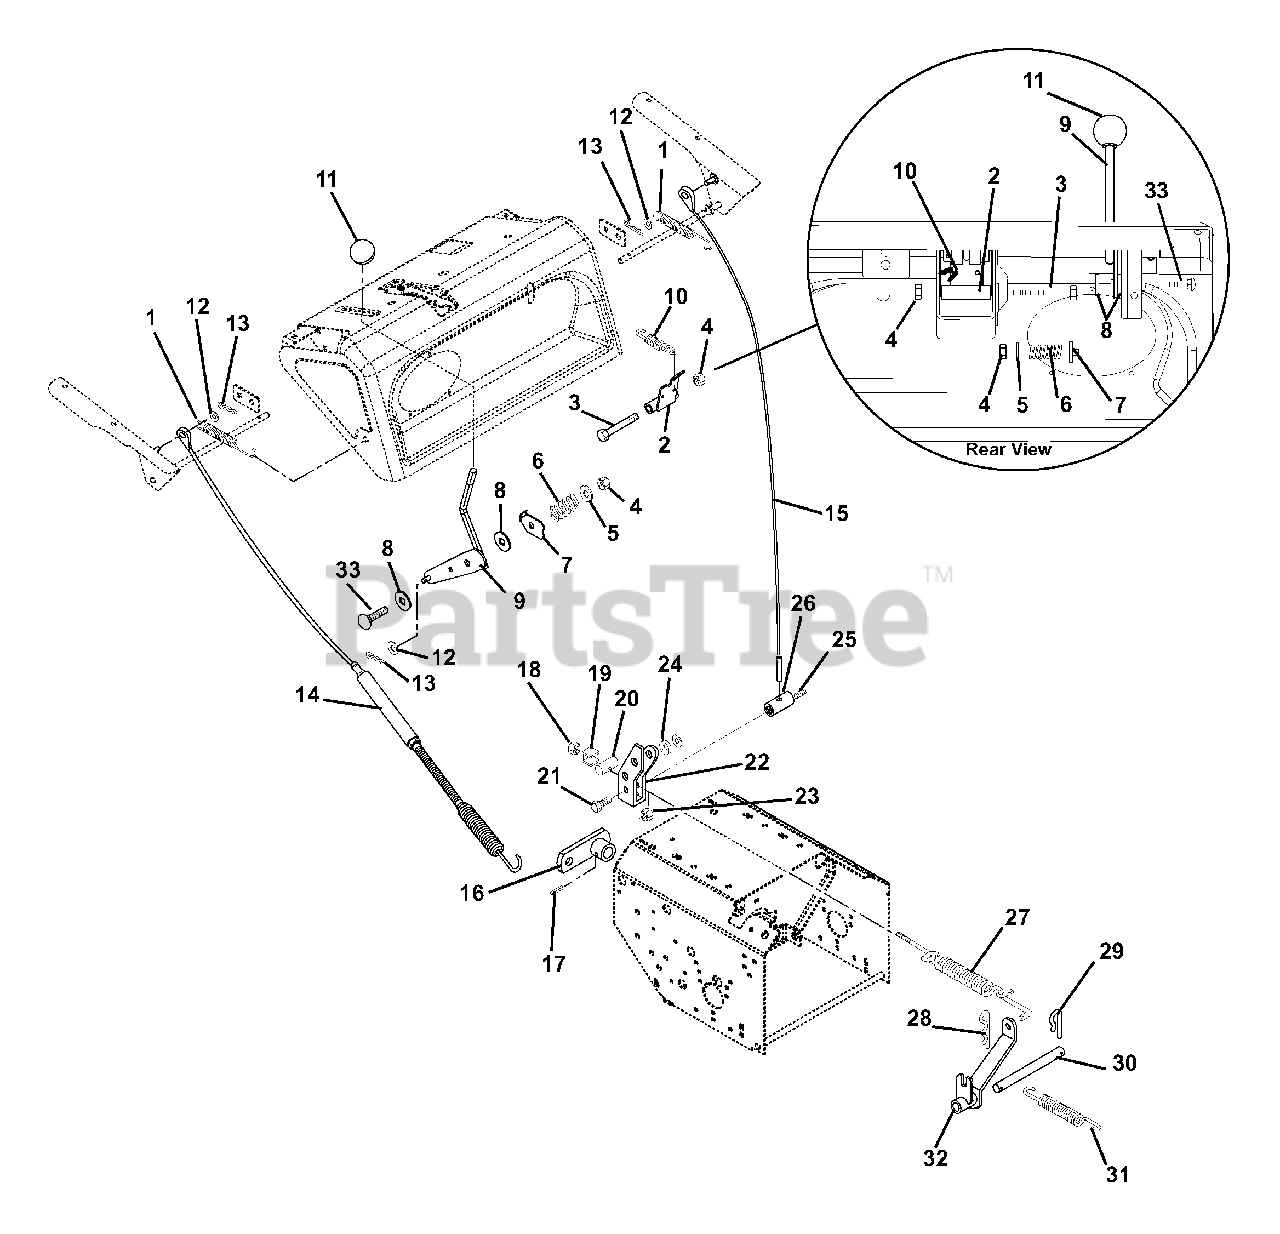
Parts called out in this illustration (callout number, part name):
1	SG-TENS .051X.50X4.87
2	ARM, INTERLOCK
3	@BLT-HEX .38-16X3.00 GR5 YWZC
4	@NUT-LK-CTR .38-16 YWZC
5	@WSHR-FL-STL.406X.812X.065 YWZ
6	SG-COMP .187X.56X1.62
7	PRESSURE FLANGE
8	FRICTION WASHER
9	LEVER, DEFLECTOR
10	SPRING-EXT .047X.438X1.45
11	KNOB,BALL -BLACK 1.47" .375-16
12	@WSHR-FL-STL.281X.62X.065 YWZC
13	PIN-HAIR INT .06X.18X.77
14	CABLE, AUGER
15	CABLE, TRACTION
16	LEVER, CLUTCH
17	PIN-ROLL .156X.88
18	@NUT-LK-NYL .312-18 YWZC
19	ADAPTER SPACER
20	ADAPTER
21	@BLT-HEX .31-18X.75 GR5 YWZC
22	CLUTCH ENGAGEMENT YOKE
23	@NUT-LK-CTR .31-18 YWZC
24	SPACER 1.00 X .64 X .38
25	SCR-SET .31-18X.38 SKHCUPDL
26	ROD ADAPTER
27	SPRING ASSEMBLY
28	PIN-HAIR INT .06X.18X.77
29	CLIP, SPRING
30	ROD, FORK PIVOT
31	SG-TENS .080X.73X3.06 WLD 20
32	FORK, CLUTCH
33	@BLT-RDHDSQNK .38-16X2.00 G5YZ
